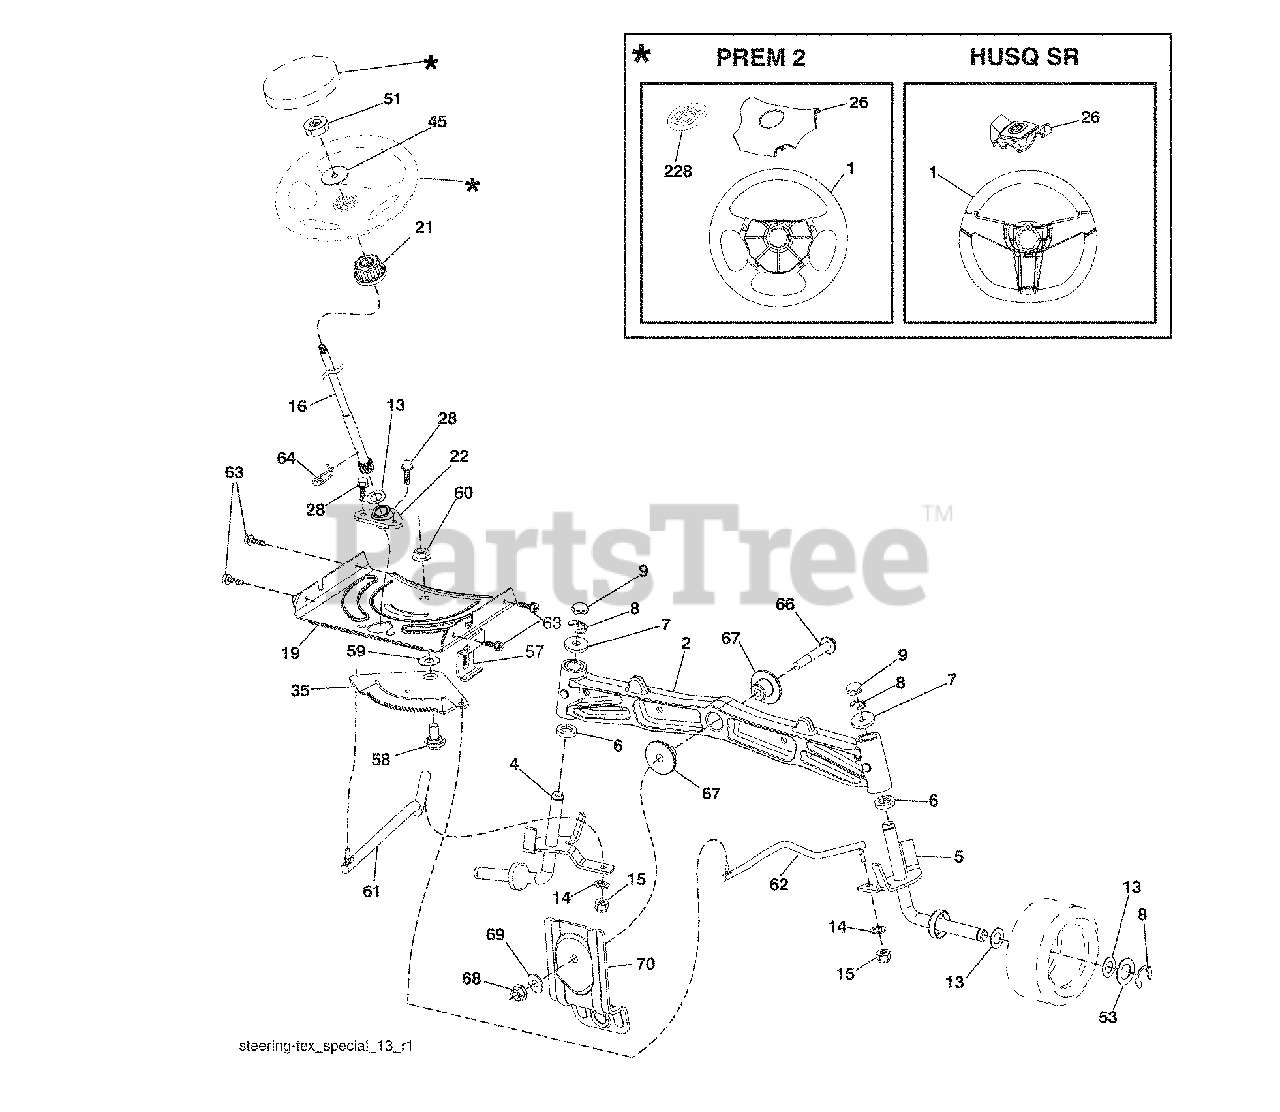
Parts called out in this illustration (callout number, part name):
1	Wheel, Steering
2	Axle Asm., Front
4	Spindle Asm., LH
5	Spindle Asm., RH
6	Bearing, Race Thrust Harden
7	Washer 25/32 x 1-5/8 x 16 Ga.
8	Ring, Klip #T5304-75
9	Cap, Spindle
13	Washer 25/32 x 1-1/4 x 16 Ga.
14	Washer, Lock Hvy Hlcl Spr 3/8
15	Nut, Crown Lock 3/8-24 unf
16	Shaft Steering
19	Plate Steering
21	Adapter, Wheel Steering
22	Bushing, Strg. Blk
26	Insert, Wheel Steering
28	Screw 3/8-16 x 3/4
35	Gear, Sector Plate
45	Washer 9/16 x 2-3/8 x 12 Ga.
51	Nut Hex Jam Toplock 1/2-20 unf
53	Washer Hardened .793 x 1.637 x .060
57	Bracket Upstop
58	Bolt Shoulder Sector Pivot CFM
59	Washer Thrust Sector Steering
60	Nut Flange Lock 5/8-11
61	Draglink LH
62	Draglink, RH
63	Screw 5/16-18 x 3/4
64	Retainer Clip Spring Steering
66	Bolt Hex Fghd 7/16-14 x 3 Serr
67	Bushing PM Front Axle
68	Nut Lock Flange 7/16-14 Gr. 5
69	Washer 1.5 x .505 x .118
70	Bracket Deck Susp. Front
228	Decal, Wheel Steering
